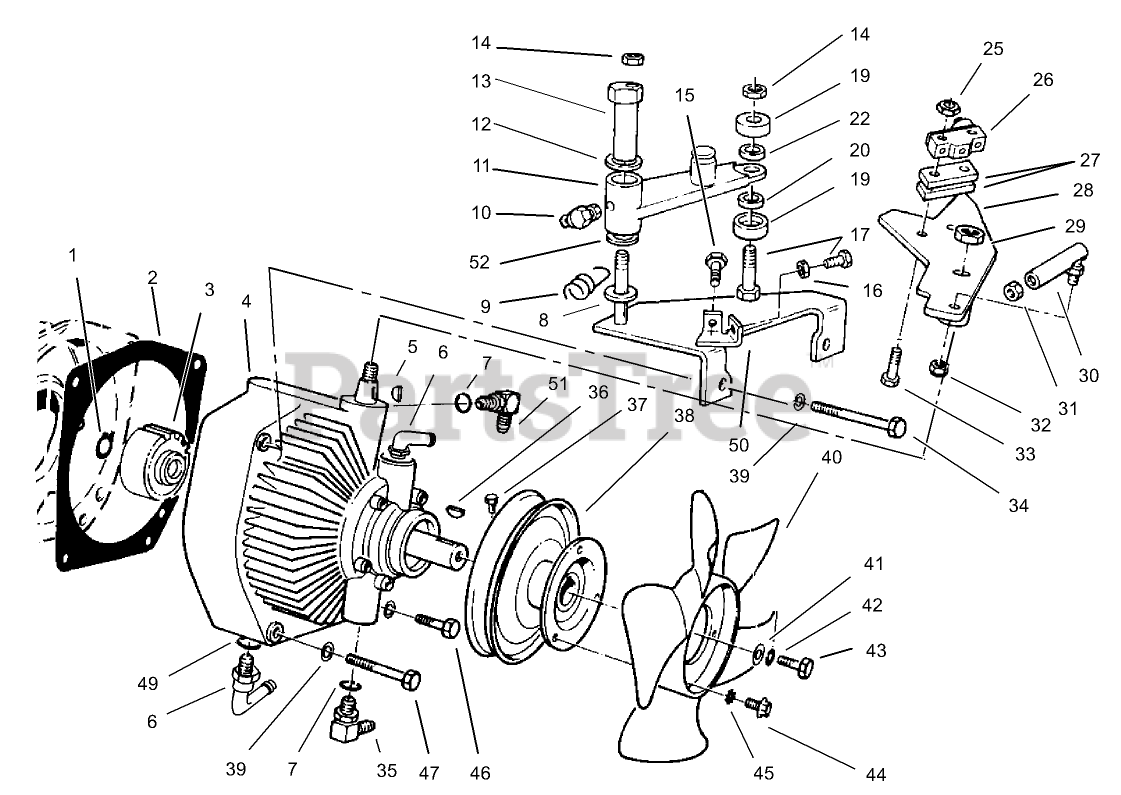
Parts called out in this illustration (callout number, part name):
1	RING-SNAP, EXTERNAL
2	TRANS GASKET
3	GEAR-SPUR
4	TRANSMISSION - HYDRO
5	KEY-WOODRUFF
6	ADAPTER
7	O-RING
8	WASHER-FLAT
9	SPRING-EXTENSION
10	FITTING-GREASE
11	Swing Arm Assembly (Incl. Ref. 10 & 52)
12	WASHER-THRUST
13	STUD-TRACTION
14	NUT-LOCK, NI
15	SCREW-HH
16	NUT-HEX
17	SCREW-HH
19	BEARING-BALL
20	SPACER
22	SPACER-BEARING
25	NUT-HEX
26	SWITCH-MICRO
27	PLATE-SWITCH
28	Lever-Traction
29	NUT-LOCK, NI
30	JOINT-BALL
31	NUT-JAM
32	NUT-LOCK
33	SCREW-PPH
34	SCREW-HH
35	Fitting-Hydraulic, 905 (Incl. Ref. #7)
36	KEY-WOODRUFF
37	SCREW-SQH
38	TRANS PULLEY
39	WASHER-LOCK
40	FAN 8"
41	WASHER-FLAT
42	WASHER-LOCK
43	SCREW-HH
44	SCREW-SHWH
45	WASHER-LOCK/EXT
46	SCREW-HH
47	SCREW-HH
49	O-RING
50	Plate-Traction
51	FITTING-ELBOW-90 DEG
52	BUSHING-FLANGE
